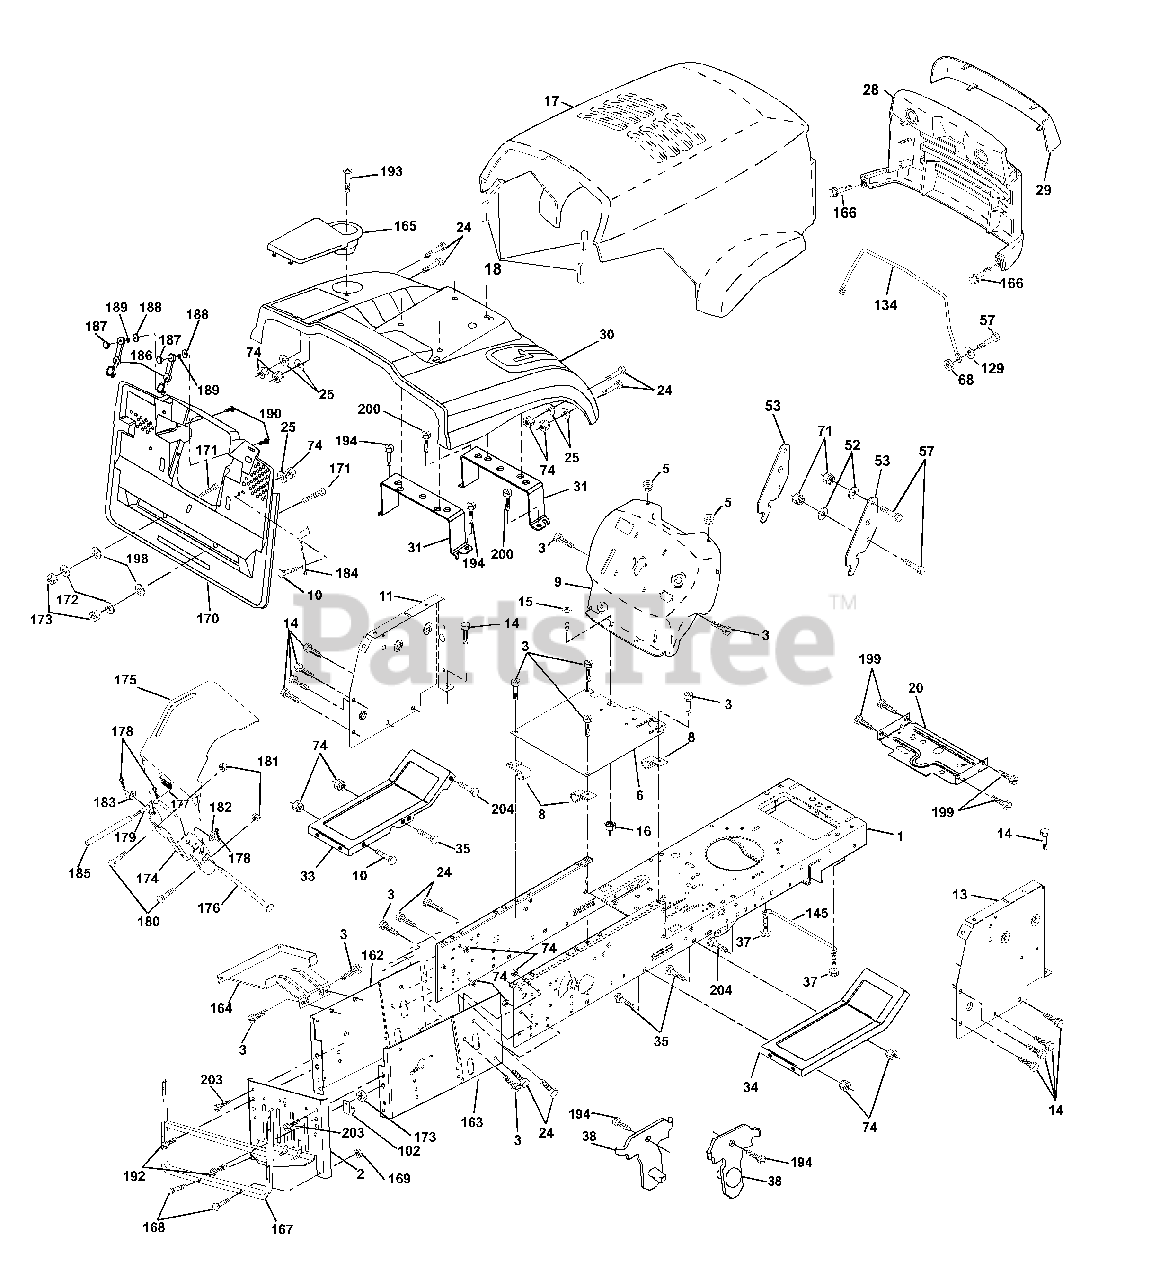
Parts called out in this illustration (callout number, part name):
1	Chassis Stamping
2	Drawbar, CRD
3	Screw 3/8-16x3/4
5	Bumper Hood/Dash
6	Saddle Flat Lt Fender Shift
8	Clip Insulator 13/32 Mtg Hole
9	Dash P/LM Slkscr Elec W/Am Sym
10	Bolt Carriage 3/8-16 x 1
11	Panel Dash Lh
13	Panel Dash Rh
14	Screw Thdrol 3/8-16 x 1/2
15	Screw Mach Trhd 5/16-18 Unc x 3/4
16	Nut Keps 5/16-18 Unc
17	Hood Pnt
18	Bumper Hood
20	Plate Mtg Battery/Fuel Tank Fr
24	Bolt Fin Hex 3/8-16 Unc x 1 Gr 5
25	Washer 13/32 X 13/16 X 12 Ga
28	Grille
29	Lens
30	Fender Auto CRD
31	Bracket Support Fender
33	Footrest Pnt Lh
34	Footrest Pnt Rh
35	Bolt Rdhd Sht Sqnk 3/8-16 x 3/4
37	Screw Thdrol 6/16-18 x 1/2 TYT
38	Bracket Asm Pivot Mower Rear
52	Washer 9/32 x 7/8 x 16 Ga
53	Bracket Pick Off Lt/PL Husq
57	Bolt Fin Hex 1/4-20 Unc x .75
68	Nut Keps Hex 1/4-20 Unc Yel D
71	Nut Crown Lock 1/4-20 Unc Blk D
74	Nut Crown Lock 3/8-16 Unc Blk D
102	Clip Line Fuel 13/32 Mtg Hole
129	Washer 9/32 x 5/8 x 16 Ga.
134	Rod Support Hood Husq P/L
145	Rod Pivot Chassis/Hood
162	Bracket Exten Chassis Lh
163	Bracket Exten Chassis Rh
164	Support Battery CRD
165	Cover Battery CRD Lt Grey
166	Screw Hwhd Hi-Lo #13-16 x 3/4
167	Support Asm Backplate Wldmnt
168	Bolt Rdhd Sht NK 1/4-20 x 1-1/2
169	Nut lock 1/4 Lge Flg Gr 5 Zinc
170	Cover Backplate Plastic Black
171	Bolt Hex 3/8-16 x 2-1/2
172	Washer 13/32 x 1-1/4 x 16 Ga
173	Nut Keps Hex 3/8-16 Unc
174	Bracket Switch FBI CRD
175	Guard Door Rear CRD
176	Pin Hinge Pivot
177	Spring Bagger Top Lh Black
178	Pin Cotter 3/32 x 3/4 Cad
179	Rod Pivot FBI CRD
180	Bolt Hex Hd 5/16-18 Unc x 1
181	Nut Crownlock 5/16-18
182	Washer .385 x .625 x 11 Ga
183	Washer 13/32 x 13/16 x 16 Ga
184	Bracket Actuator Bagger CRD
185	Tube Lever Swch FBI CRD 2-1/16
186	Latch Asm Mulch/Bagger
187	Nut Weld .327/.304 #10-24
188	Washer #10
189	Washer Lock #10
190	Screw Truss Hd Phil 10-24 x 5/8
192	Screw Thdrol 3/8-16 x 1-1/2
193	Screw Truss 1/4-20 x 3/4 Tap/R
194	Screw 3/8-16 x .75
199	Screw Thdrol 5/16-18 x 1/2 Tytt
200	Screw 3/8-16 x .75
203	Screw Thdrol 3/8-16 x 3/4 TYTT
204	Screw Thdrol 3/8-16 x 3/4 TYTT
